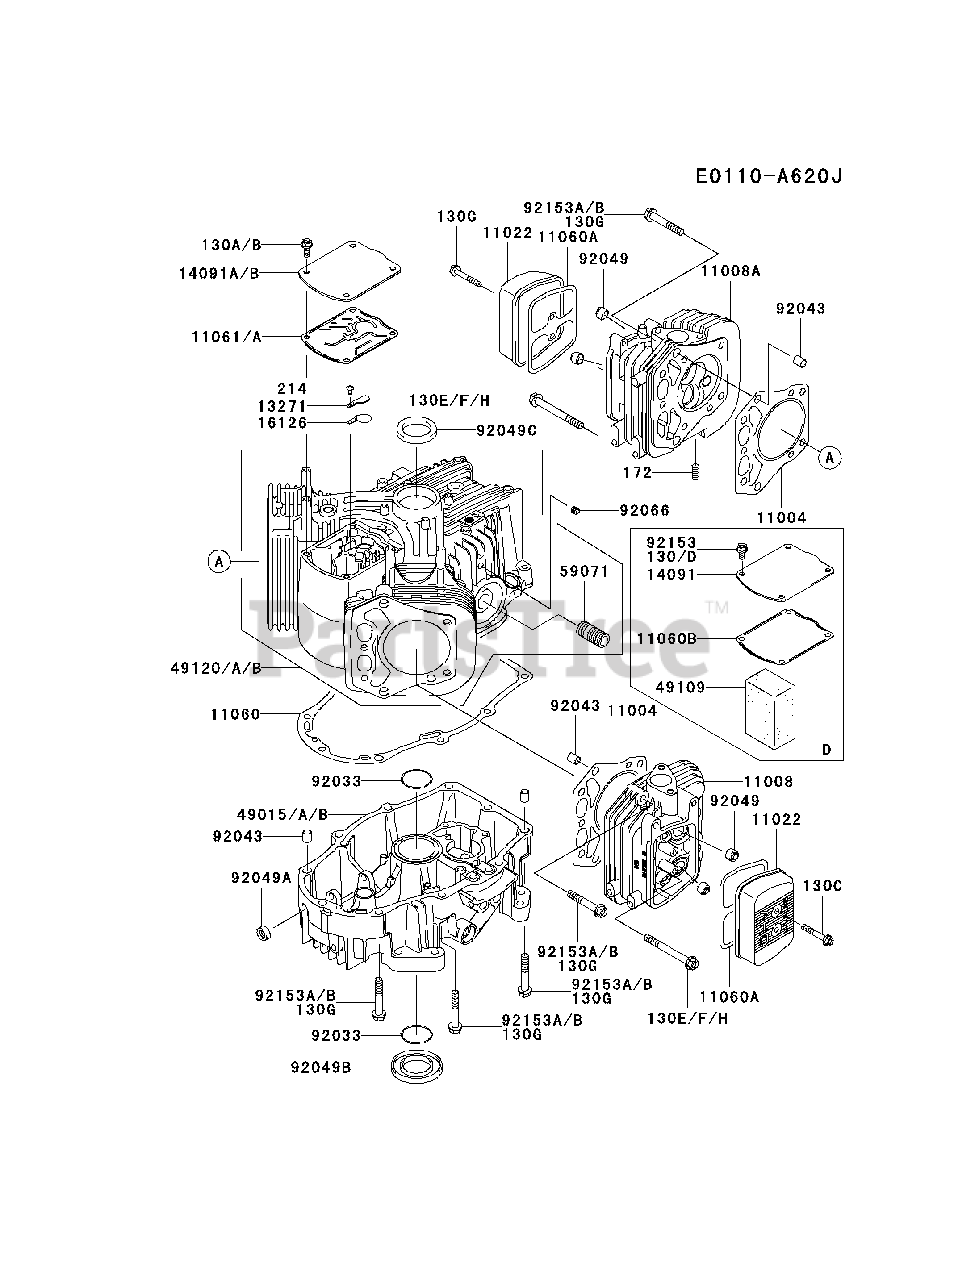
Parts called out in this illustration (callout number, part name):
130B	BOLT-FLANGED,6X16
130C	BOLT-FLANGED,6X40
130D	BOLT-FLANGED,6X12
130F	BOLT-FLANGED,8X75
130G	BOLT-FLANGED,8X50
130H	BOLT-FLANGED,8X75
172	BOLT-STUD,8X18
214	SCREW-PAN+-,4X8
